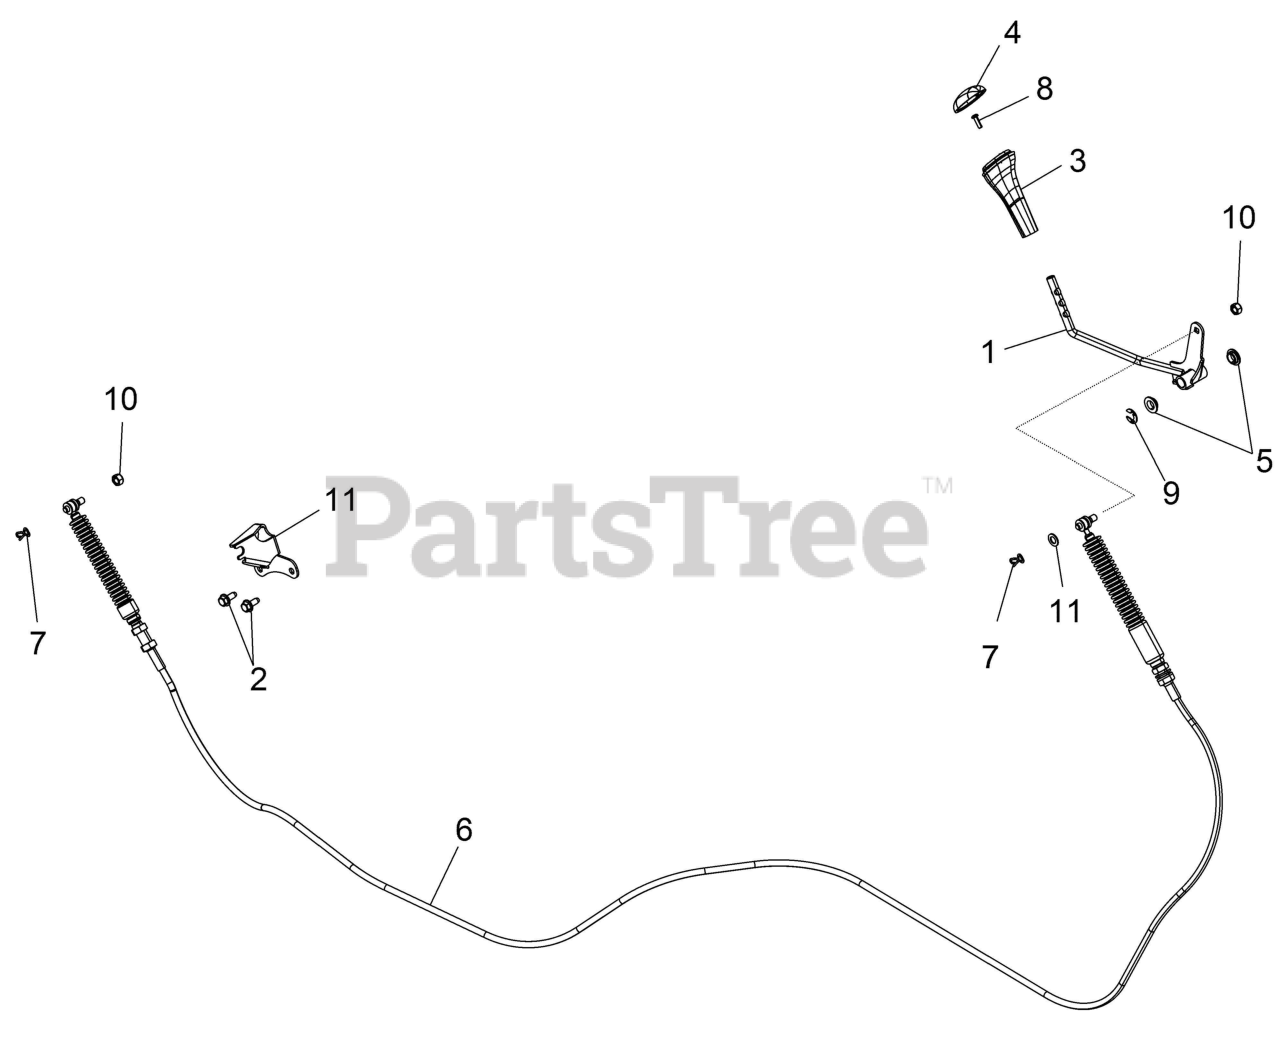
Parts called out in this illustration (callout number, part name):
1	WELD-SHIFT LEVER,BLK
2	BOLT-M10X1.25X16,HXHD,FLG
3	KNOB-GEAR SELECTOR SHIFT
4	COVER-SHIFT
5	BUSHING-PEDAL PIVOT
6	CABLE, SHIFT
7	PIN-CLIP,14MM
10	NUT,NYLOK M8X1.25(10) *
11	BRKT-SHIFT CABLE
